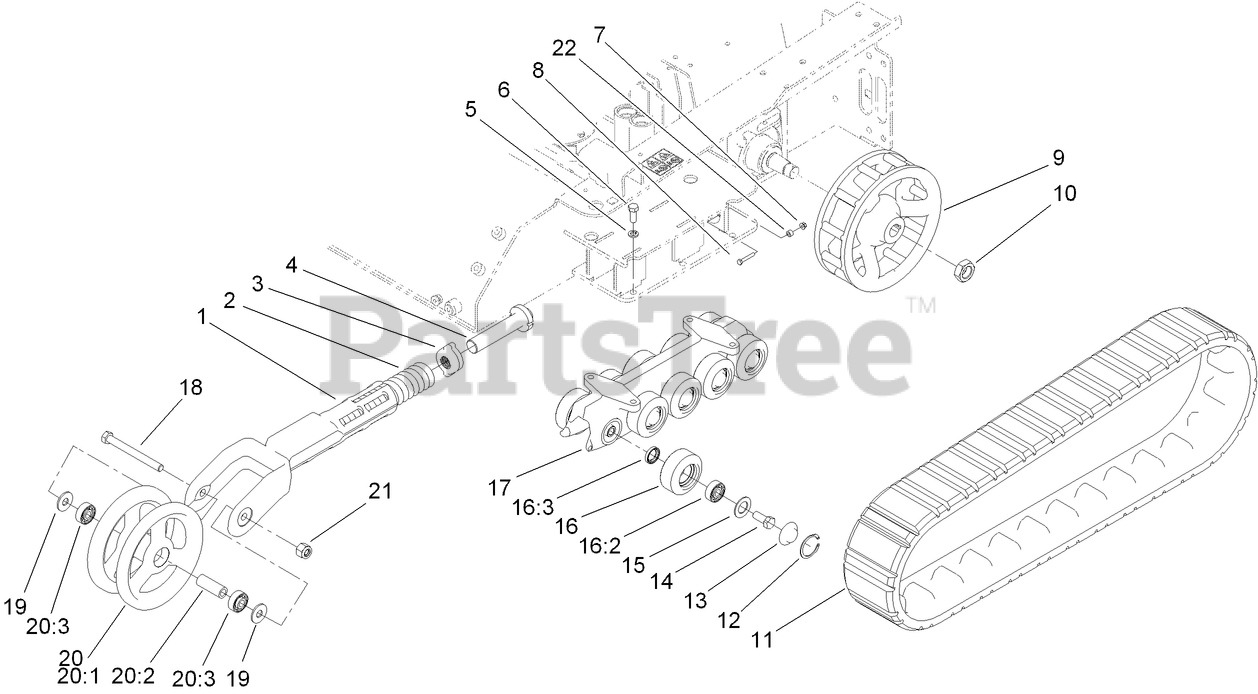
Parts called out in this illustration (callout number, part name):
1	ARM-TENSIONER
2	SPRING-COMPRESSION
3	BLOCK-TENSIONER
4	BOLT-TENSIONER
5	WASHER-LOCK
6	SCREW-HH
7	NUT-HHF
8	SCREW-HH
9	WHEEL-DRIVE
10	NUT-HEX
11	TRACK
12	RING-SNAP, INTERNAL
13	CAP-WHEEL, BEARING
14	SCREW-HH
15	Gasket-Bogie
16	Road Wheel ASM
16:2	BEARING
16:3	SEAL-OIL
17	GUIDE-TRACK
18	SCREW-HH
19	WASHER-FLAT
20	TENSIONER WHEEL ASM
20:1	WHEEL-TENSIONER
20:2	SPACER-WHEEL, TENSIONER
20:3	BEARING
21	NUT-HEX
22	SPACER
